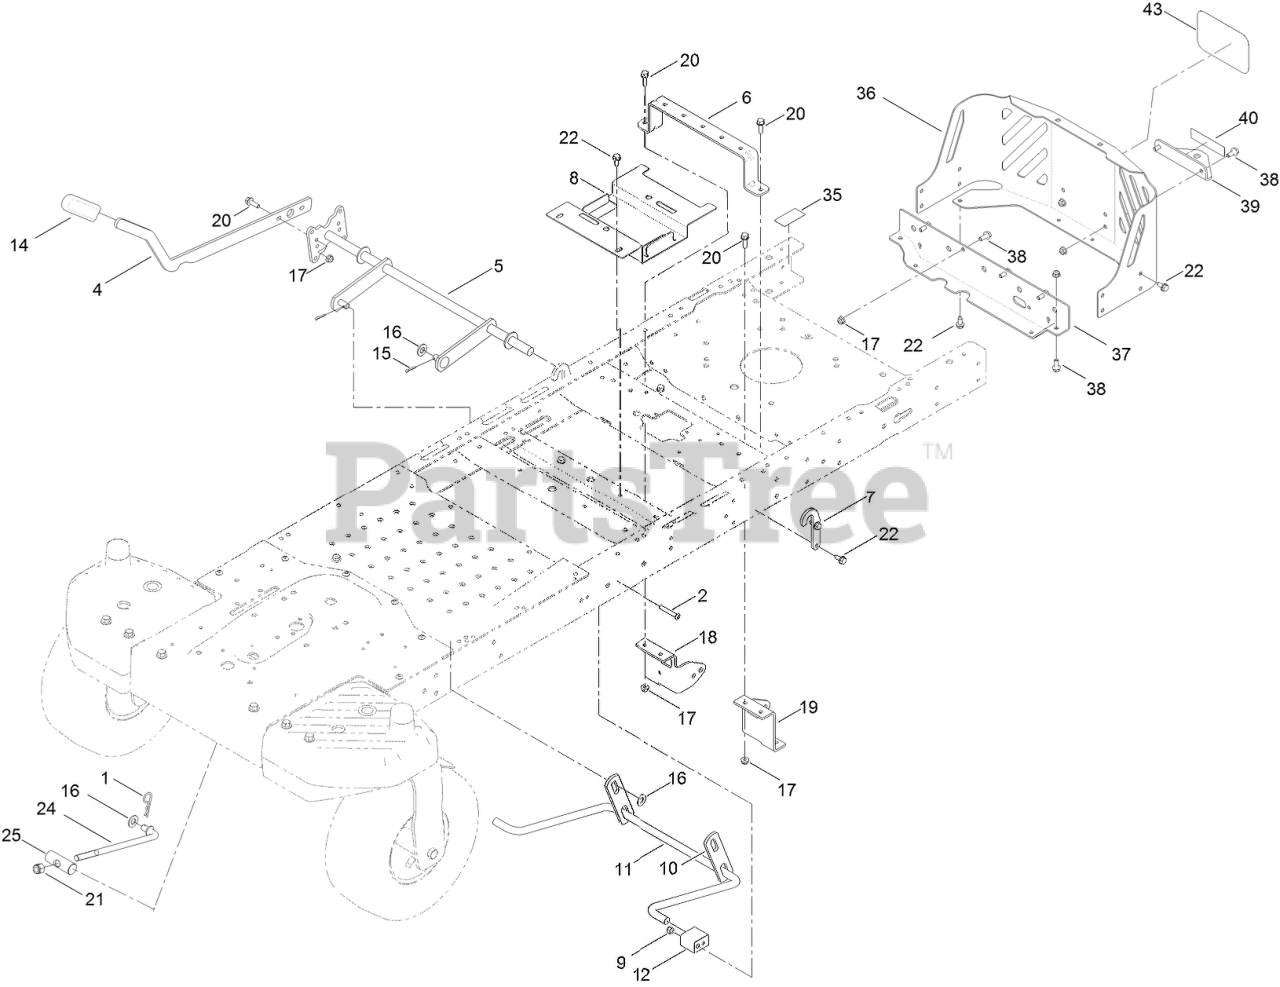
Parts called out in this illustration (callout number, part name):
1	PIN-COTTER
2	SCREW-HSBH
4	LEVER-LIFT
5	LIFT-DECK, WIDE
6	BRACE-SEAT, REAR
7	BRACKET-LIFT
8	BRACKET-BATTERY
9	NUT-LOCK, NI
10	LINK-LIFT
11	ARM-LIFT, REAR (WIDE)
12	BLOCK-PIVOT
14	GRIP-LEVER
15	PIN-COTTER
16	WASHER-FLAT
17	NUT-HF, NI
18	MOUNT-HYDRO, FRONT (RH)
19	MOUNT-HYDRO, FRONT (LH)
20	SCREW-HHF
21	NUT-HEX
22	SCREW-HWHTF
24	ROD-MOUNT, DECK
25	PIN-PIVOT
35	DECAL-BYPASS
36	GUARD-ENGINE, WIDE
37	CROSSMEMBER-REAR, WIDE
38	SCREW-HHF
39	BRACKET-HITCH
43	DECAL
